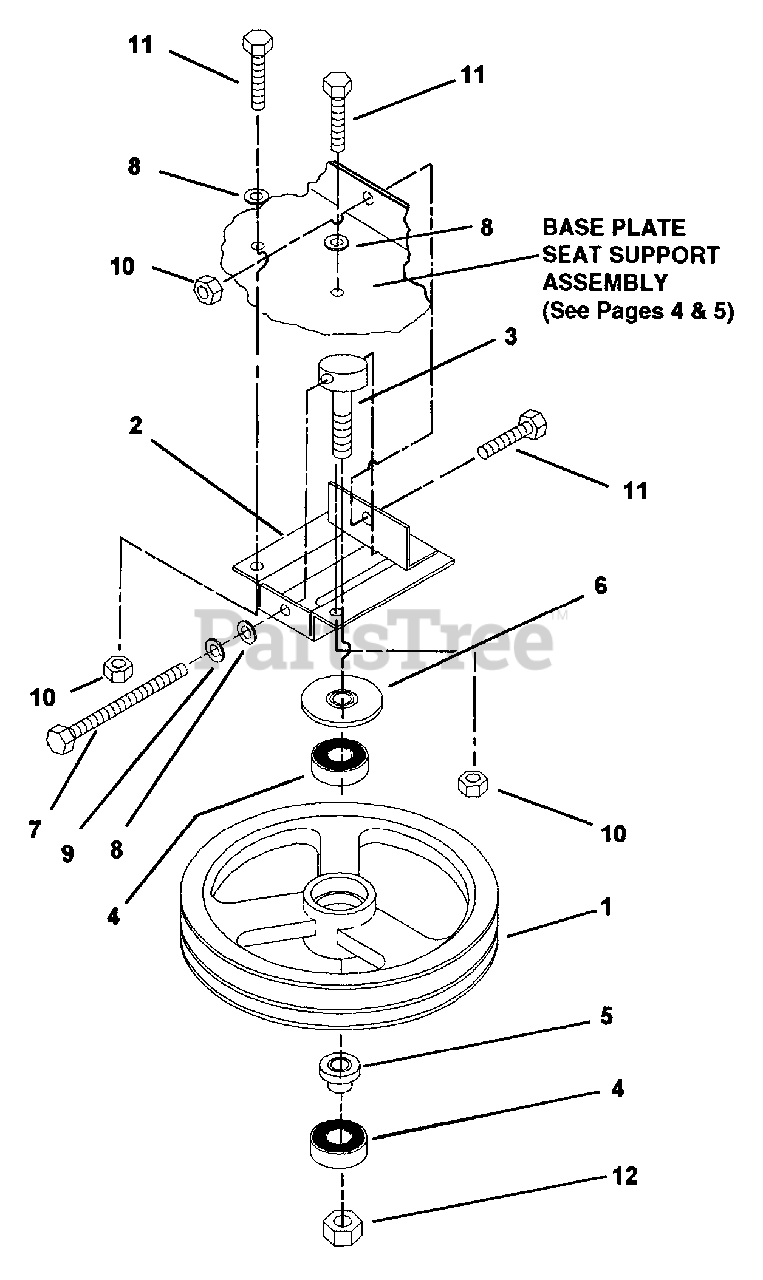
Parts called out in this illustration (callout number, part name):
1	IDLER, TWO GROOVE. 8-3/4
2	IDLER, MTG BRACKET
3	IDLER, MTG STUD
4	BEARING, #6203-2RS
5	IDLER STAND
6	IDLER, MTG SPACER
7	HEX TAP BOLT 5/16 X 4-1/2
8	WASHER, FLAT STD, STEEL 5/16
9	LOCK WASHER, 5/16 HEAVY SPRING
10	NUT, HEX 5/16-18 NYLOC
11	CAP SCREW, HH 5/16-18 X 3/4 GR. 5
12	LOCKNUT, 1/2/-13; NYLOC
